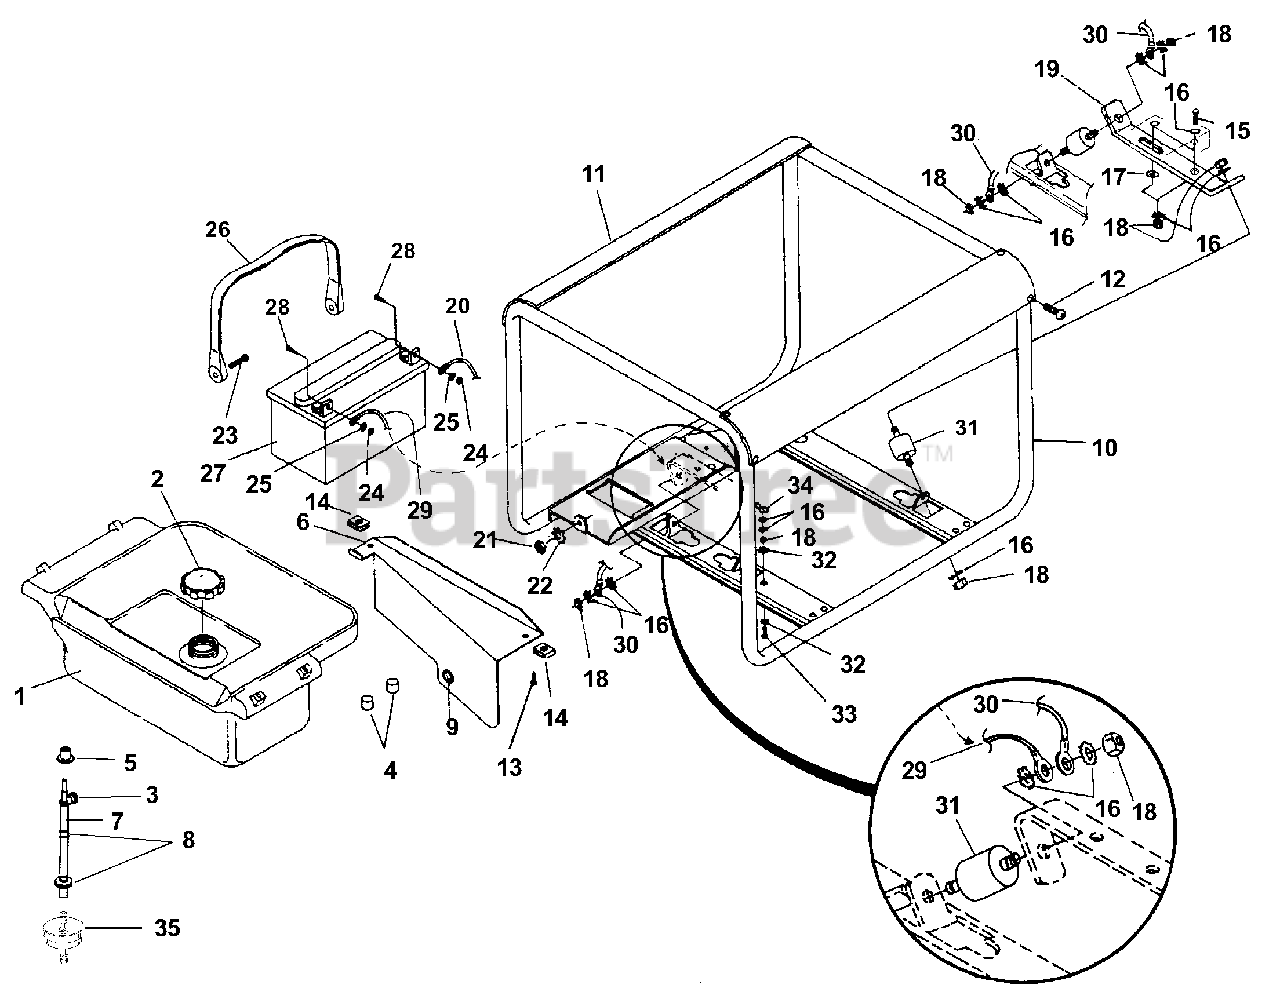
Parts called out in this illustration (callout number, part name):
1	FUEL TANK (5 Gal.)
2	FUEL CAP (2 1/4" dia.)
3	VALVE-Fuel
4	PAD-Fuel Tank
6	SHIELD-Fuel Tank
7	FUEL LINE
8	CLIP-Hose
9	BUSHING-Snap In
10	ROLL CAGE
11	BRACE-Tank Support
12	SCREW-Torx (10-24 X 1/2")
13	SCREW-Pan Hd. (8-32 X 3/8")
14	NUT-Hi Speed
15	SCREW-Hex Hd. (5/16-18 X 2")
16	WASHER-Lock (int.)
17	WASHER-Flat
18	NUT-Hex (5/16-18)
19	SUPPORT-Engine
20	CABLE-Battery (Red, Pos.)
21	NUT-Hex (10-32)
22	WASHER-Lock
23	SCREW-Shoulder (10-32 X 1/4")
24	NUT-Hex (10-32)
25	WASHER-Lock
26	STRAP-Battery Hold Down
27	BATTERY (12 Volt)
28	SCREW-Hex Hd. (1/4-20 X 5/8")
29	BATTERY CABLE (Black, to Ground)
30	GROUND STRAP
31	ISOLATOR
32	WASHER-Lock (ext./int.)
33	SCREW-Hex Hd. (5/16-18 X 1 1/2")
34	NUT-Wing
35	Fuel Filter
